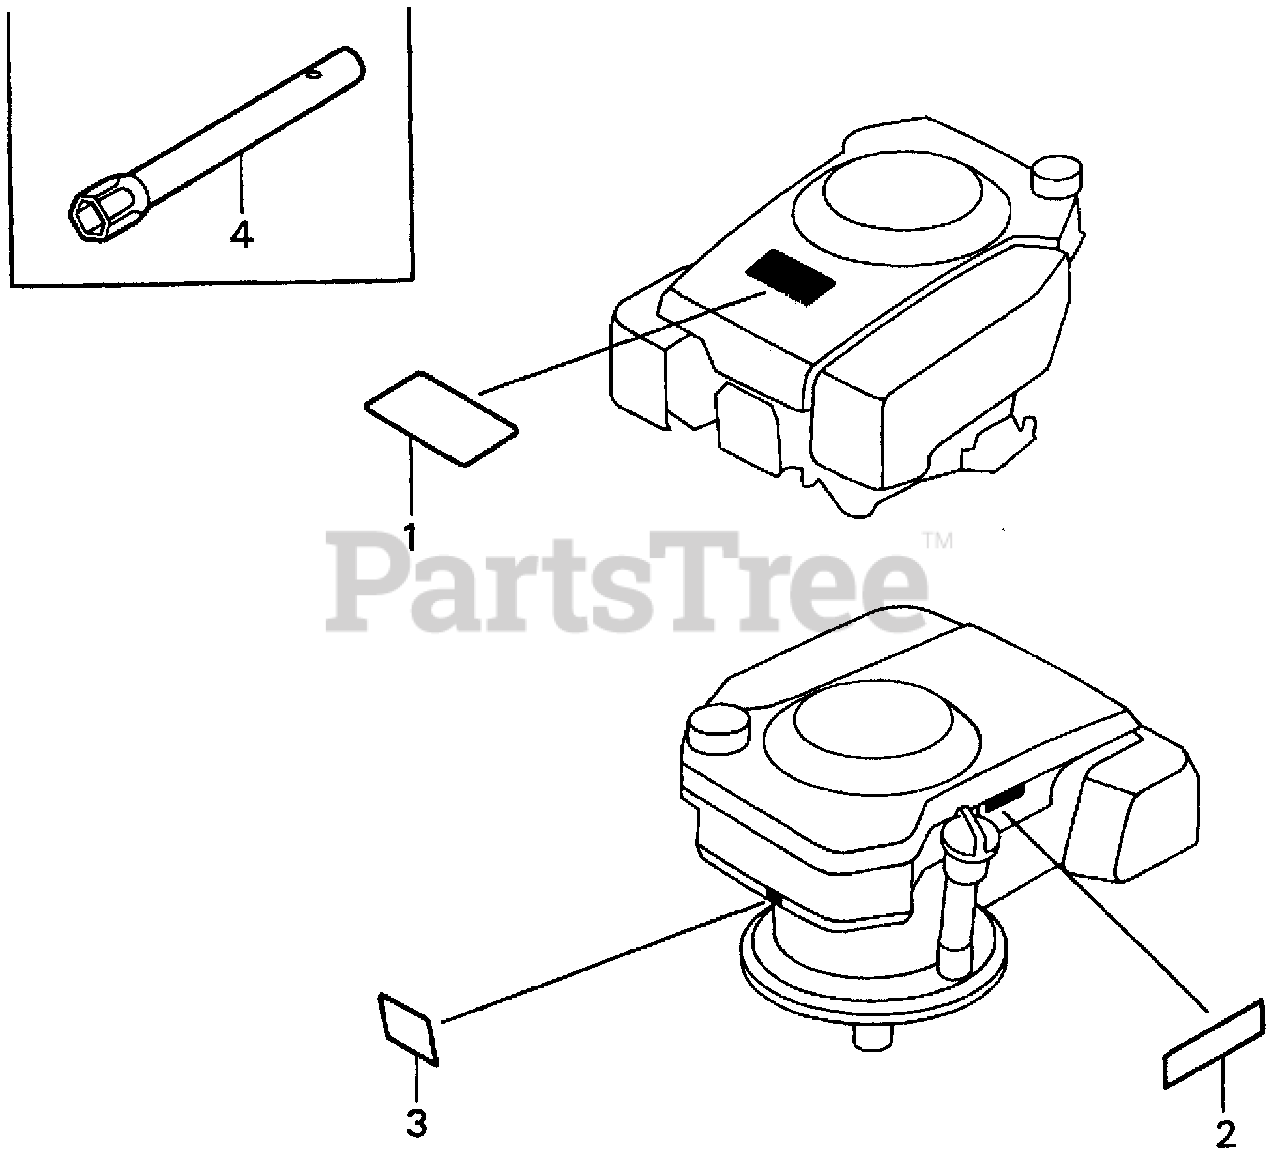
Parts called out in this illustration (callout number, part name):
1	MARK, EMBLEM (5.5 ES)
2	MARK, HONDA
3	MARK, TYPE (N62)
4	WRENCH, BOX (P21)
